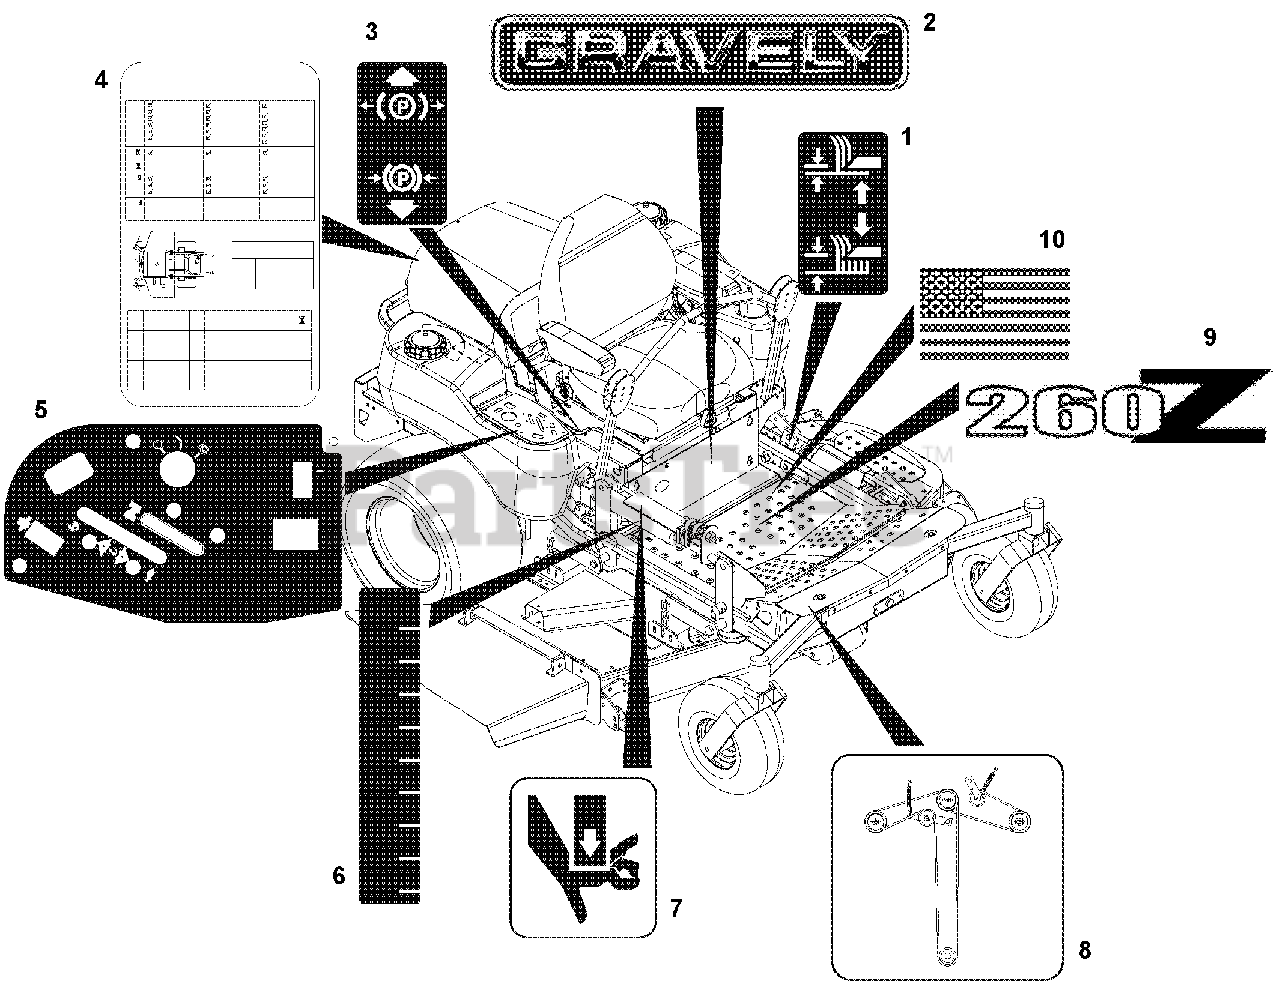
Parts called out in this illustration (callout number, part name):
1	Decal, Lift Lever
2	Decal, 15 Gravely Logo
3	Decal, Parking Brake Lever
4	Decal, Service Instructions
5	Decal, Control Panel (045, 046, 047, 049, 052, 053)
6	Decal, Height of Cut
7	Decal, Pinch Point
8	Decal, Belt Diagram (045, 046, 047, 048, 052)
9	Decal, PM-260Z (046, 047, 048)
10	Decal, American Flag
